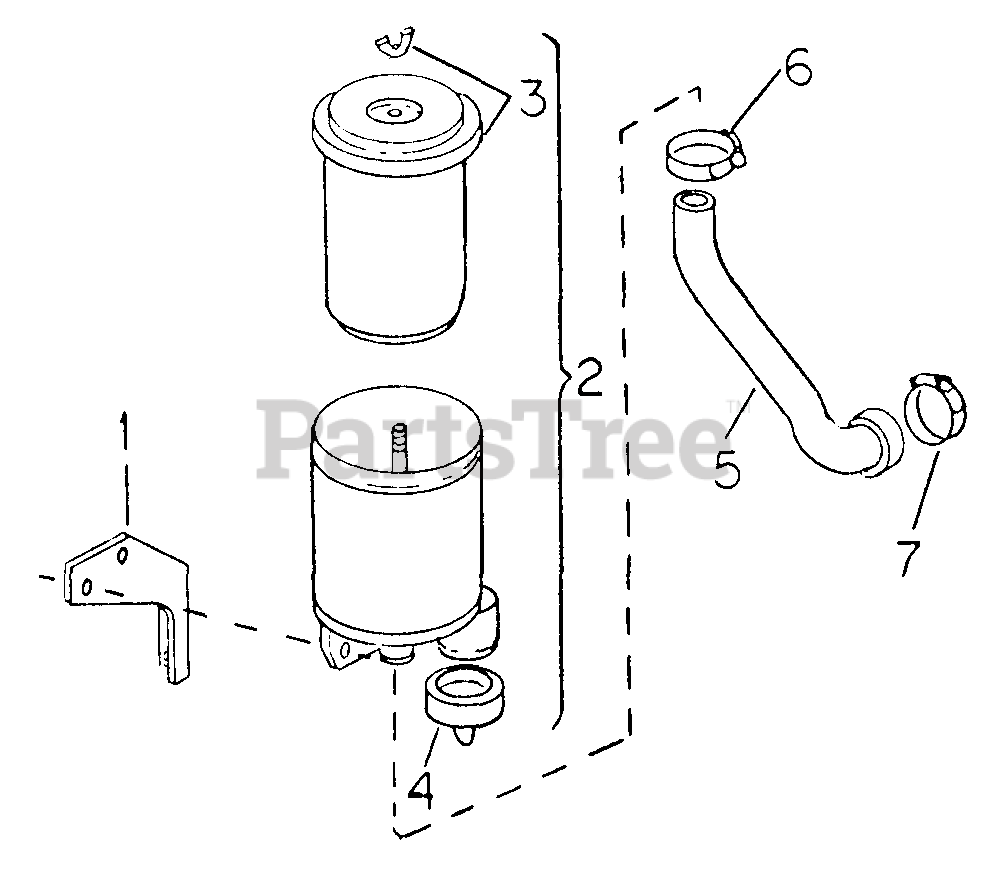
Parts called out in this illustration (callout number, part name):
1	BRACKET ASSY, AIR CLEANER
2	CLEANER ASSY, 5-1/4 IN DIAMETER DRY TYPE AIR
3	ELEMENT W/WING NUT, AIR CLEANER
4	VALVE, RUBBER UNLOADER
5	HOSE, AIR CLEANER
6	CLAMP, AIR CLEANER HOSE AIR - CLEANER END
7	CLAMP, AIR CLEANER HOSE - CARBURETOR END
